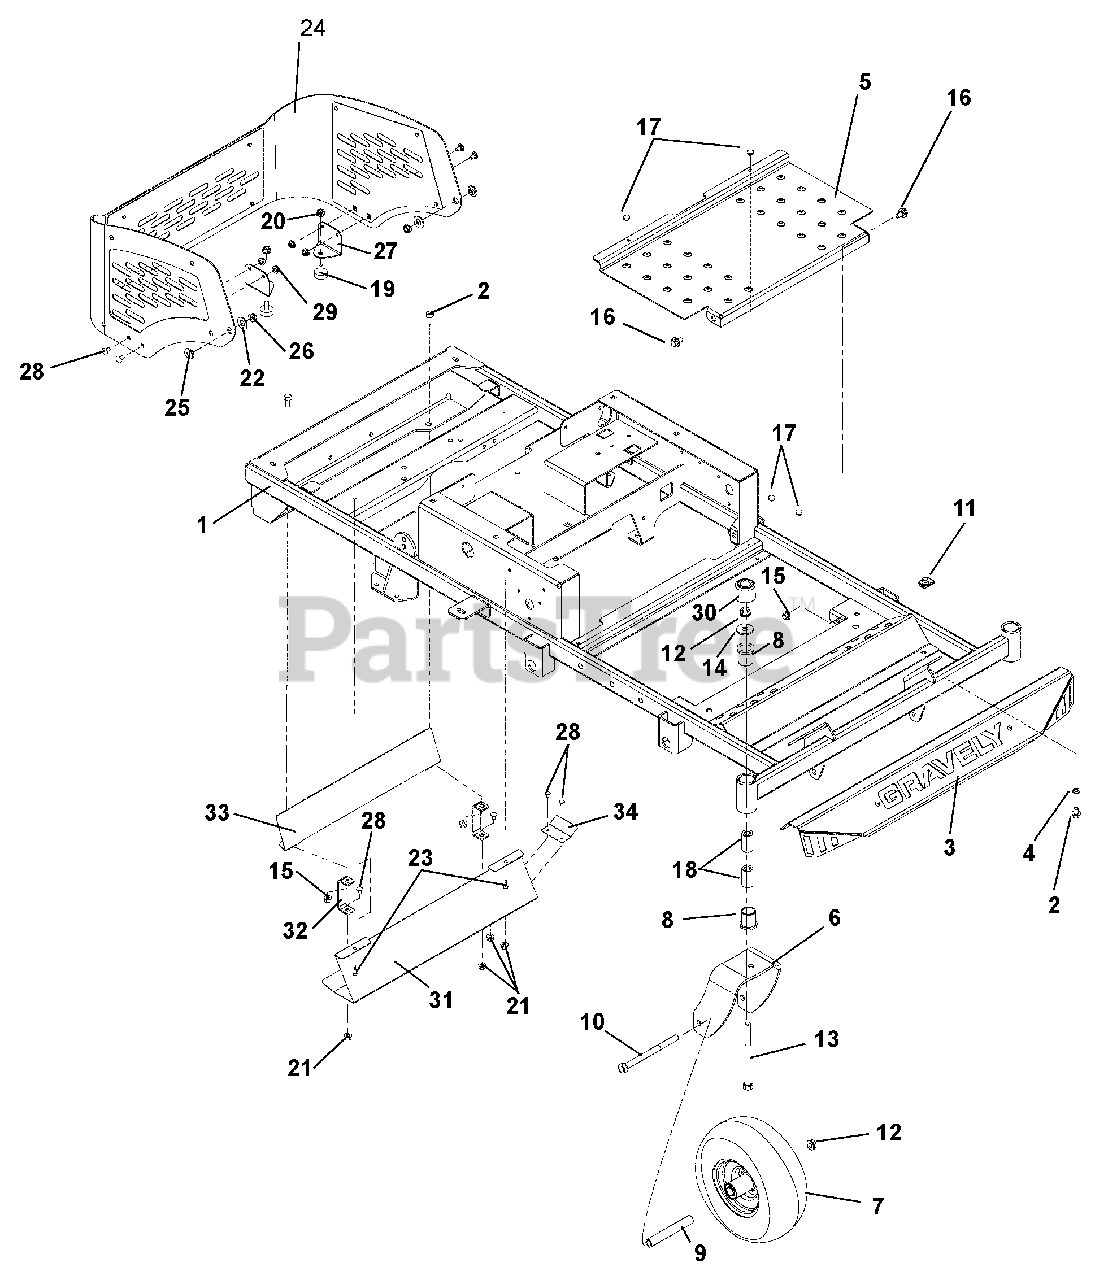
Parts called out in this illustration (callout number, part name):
1	WLDMT, FRAME ZT/ZOOMXL (2013)
2	BLT-HEX .38-16X1.00 GR5 YWZC
3	ASM, FOOT-REST XL
4	WSHR-LK .38X.094 REG YWZC
5	DECK ACCESS PANEL
6	WMT, CASTER FORK
7	TIRE/WHEEL ASSY, 11X4-5
8	BSHG-FLG 1.00X1.25X1.50X1.50
9	SPACER, ROLLED WHEEL
10	BLT-HEX .50-13X6.50 GR5 YWZC
11	NUT-RTNR .375-16X.37
12	NUT-LK-TOP-FLG .50-13 YWZC
13	BLT-HEX .50-13X5.00 GR5 YWZC
14	WSHR-FL-STL.511X1.441X.125 YWZ
15	NUT-LK-TOP-FLG .38-16 YWZC
16	BOLT-SHLDR .375-16X.150
17	BUMPER GROMMET
18	SPACER, CASTER .50X1.00X1.84
19	BUMPER, RUBBER
20	NUT-SPNLK-FLG .312-18 YWZC
21	NUT-LK-TOP-FLG .25-20 YWZC
22	WSHR-FL-NYL .518X1.000X.080
23	SCR-TAP .25-20X.50 HWH TR YWZ
24	ASM, ENGINE WRAP XL
25	BSHG-FLG .325X.499X.3X.875
26	NUT-LK-CTR-FLG .31-18 YZ GR F
27	BRKT, XL ENGINE WRAP FOOT
28	BLT-RDHDSQNK .25-20X.50 G5YZ
29	NUT-LK-CTR-FLG .25-20 YWZC
30	CAP, DUST
31	GUARD, MUFFLER HEAT
32	STRAP, MUFFLER GUARD
33	SHIELD, HOT SURFACE
34	DEFLECTOR, HEAT SHIELD
